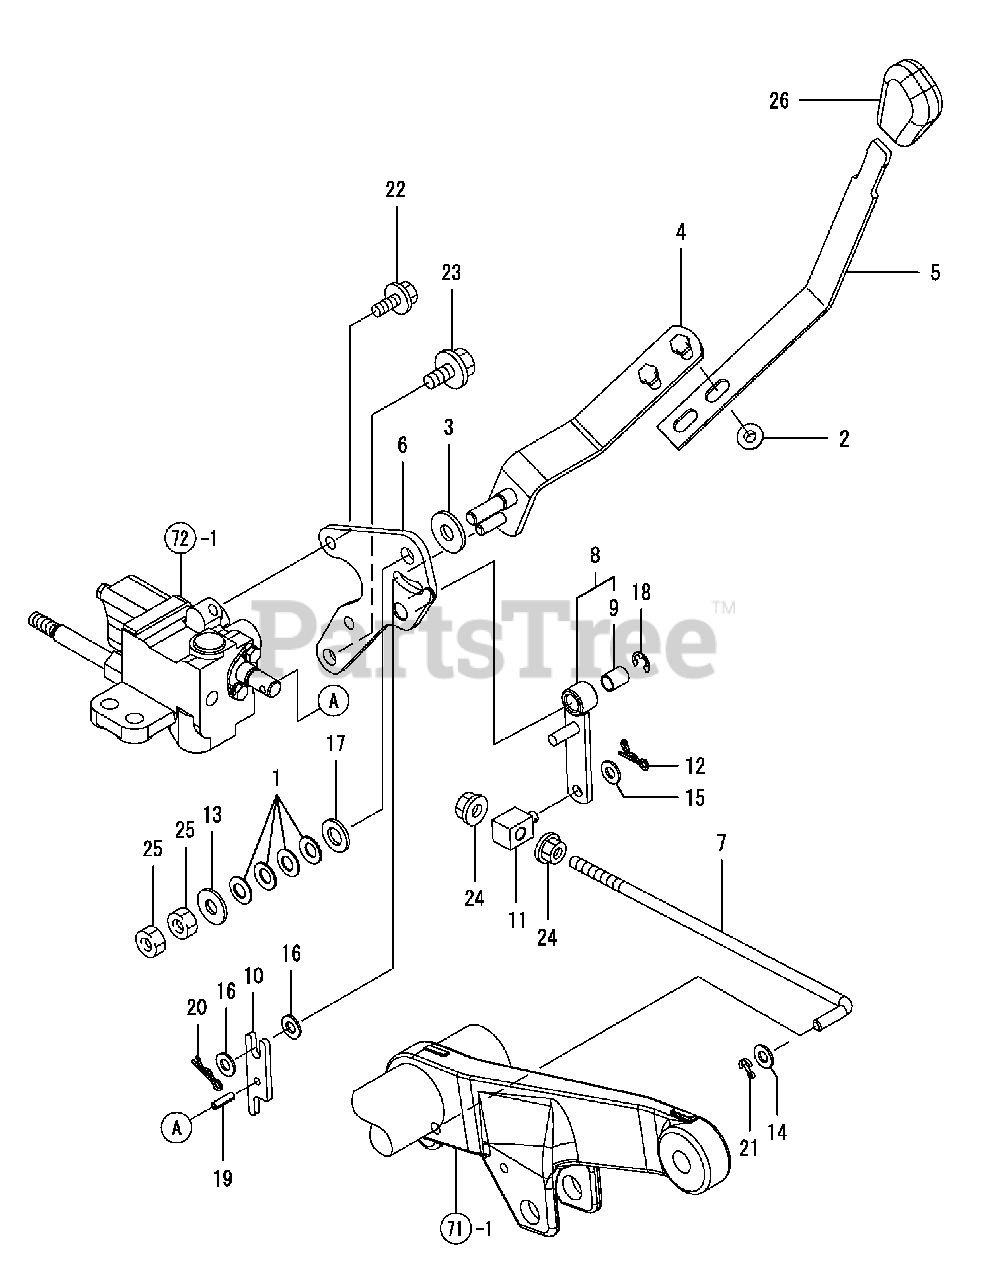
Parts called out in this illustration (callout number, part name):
1	WASHER 10, CONICAL
2	NUT W/WASHER 8
3	PLATE, FRICTION
4	LEVER CMP, POSITION
5	LEVER, POSITION
6	STAY CMP, HYD. LINK
8	LEVER ASY, CONTROL
12	PIN 8, COME-OFF SNAP
14	WASHER 8, POLISHED
15	WASHER 8, POLISHED
16	WASHER 8, POLISHED
17	WASHER 12, POLISHED
19	SPRING PIN 5X18
20	SNAP PIN (JASO 8)
21	COTTER PIN 2.0X16
22	BOLT M 8X 16 PLATED
23	BOLT M10X 20 PLATED
